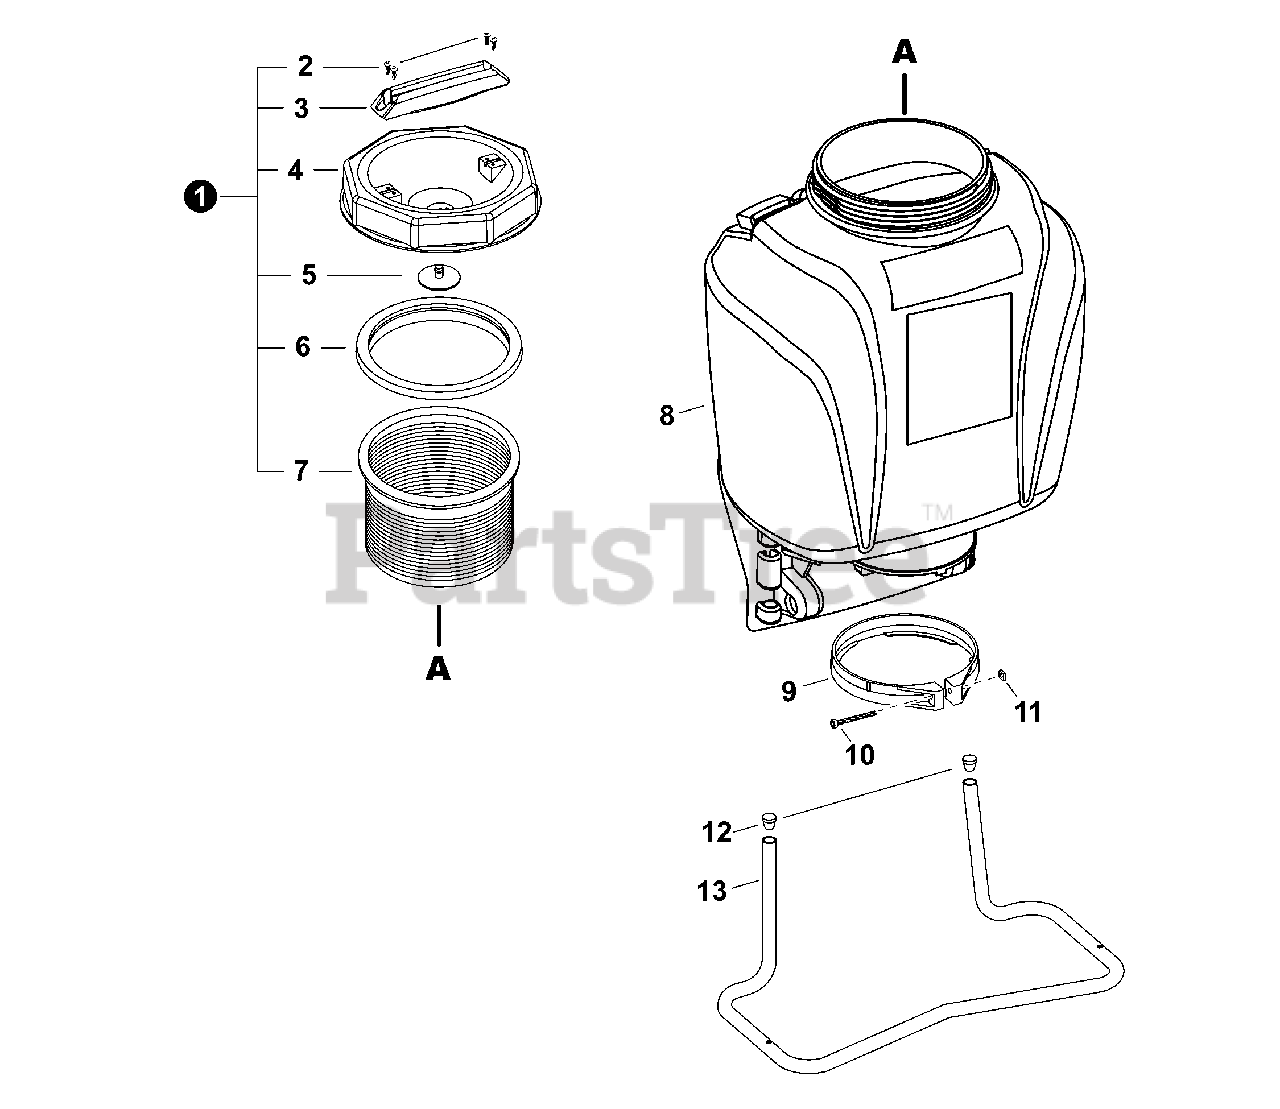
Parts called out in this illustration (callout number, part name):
1	CAP KIT, TANK
2	SCREW
3	HANDLE
4	CAP, TANK
5	VALVE, CHECK - CAP
6	GASKET, BASKET
7	BASKET, FILTER
8	TANK, SPRAYER
9	CLAMP, PUMP
10	SCREW, CLAMP
12	CAP, BASE
13	BASE, TANK
